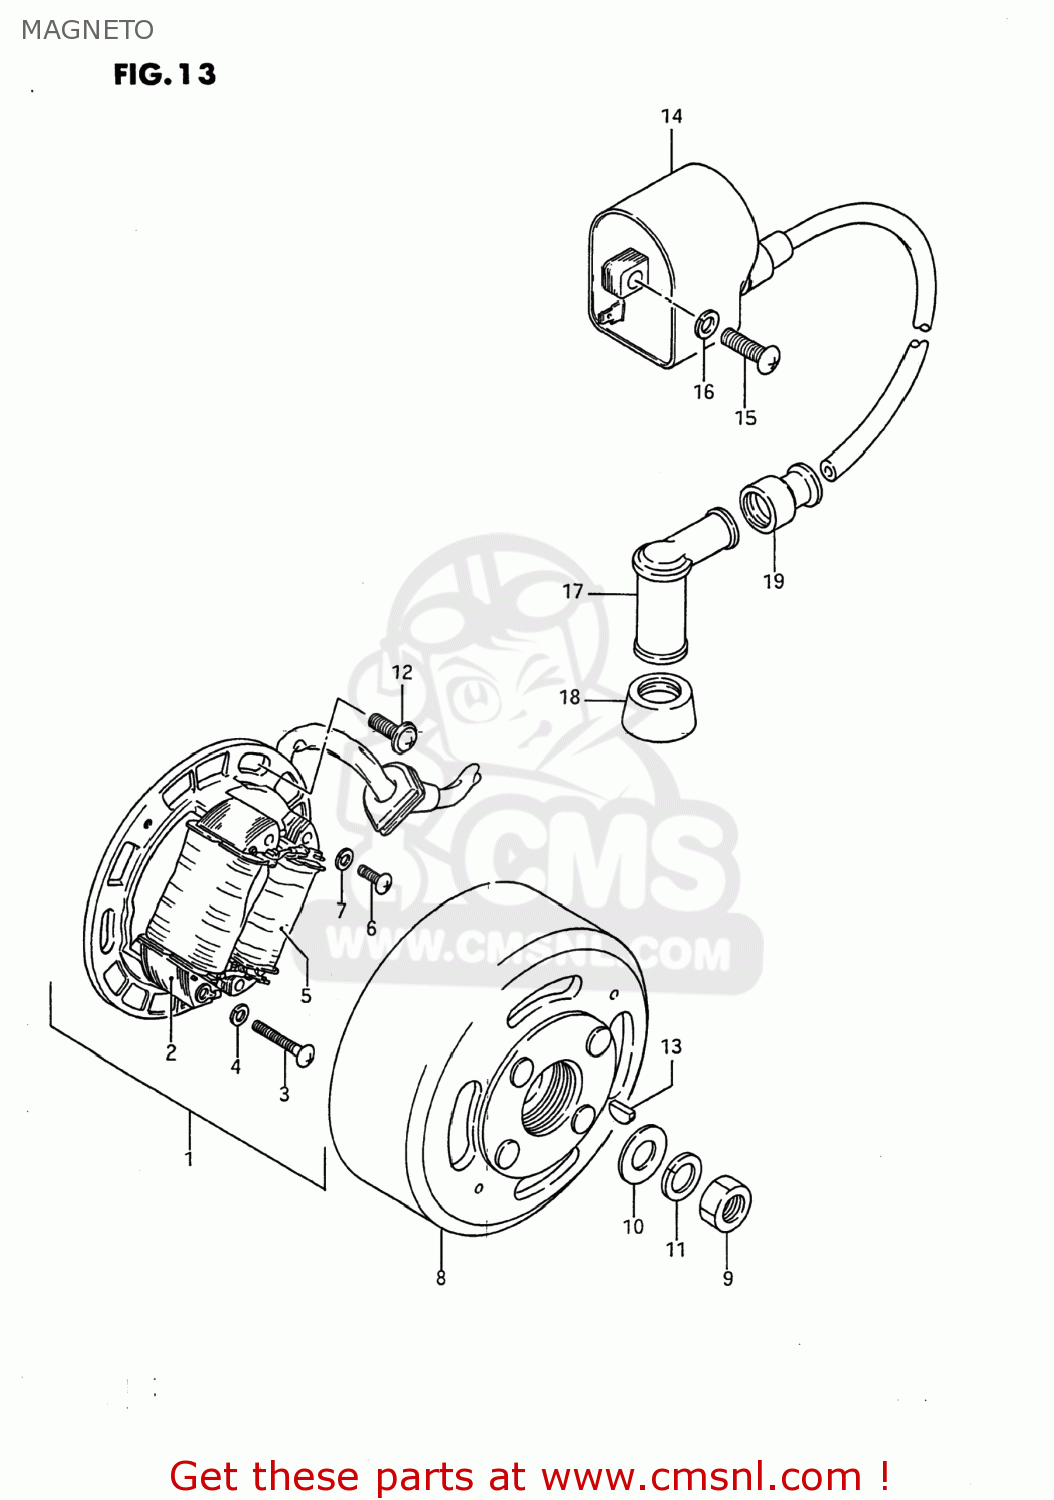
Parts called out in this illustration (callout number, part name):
1	STARTER ASSY
2	COIL,LIGHTING
3	SCREW
4	WASHER,LOCK
5	COIL,PRIMARY
6	SCREW
7	WASHER,LOCK
8	ROTOR,FLYWHEEL
9	NUT
10	WASHER
11	WASHER
12	SCREW
13	KEY
14	UNIT & COIL ASSY,IGNITION
15	SCREW
16	WASHER,LOCK
17	CAP,SPARK PLUG
18	SEAL,SPARK PLUG
19	SEAL,HIGH TENSION CORD
